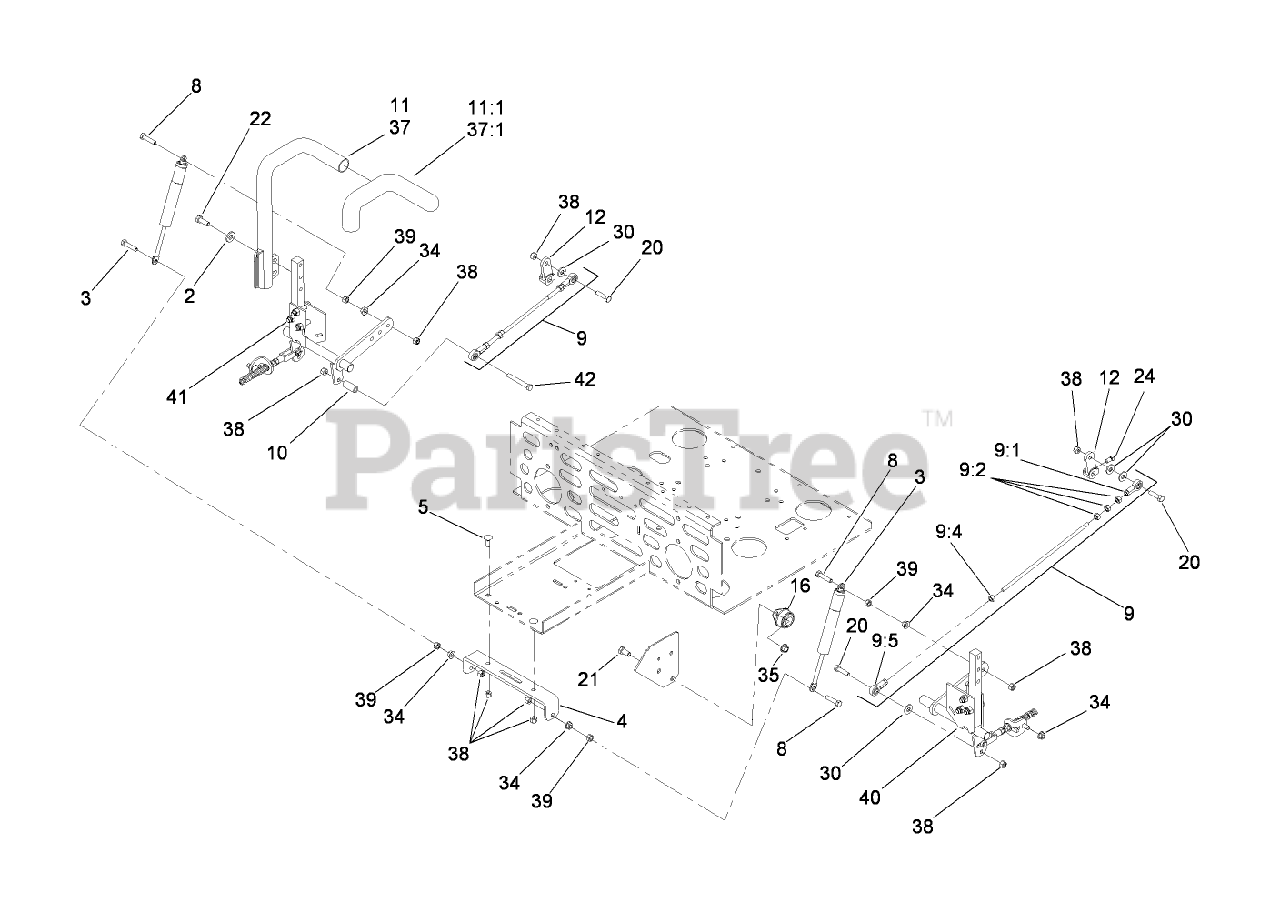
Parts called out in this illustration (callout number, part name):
2	WASHER-BELLEVILLE
3	DAMPER-CONTROL, MOTION
4	BRACKET-MOUNT, DAMPER
5	SCREW-CARR
8	SCREW-HH
9	Tracking Rod ASM
9:1	BALLJOINT-RH
9:2	NUT-HEX
9:5	BALLJOINT-LH
10	SPACER
11	LH LEVER ASM
11:1	Grip-Control, Motion
12	ARM-CONTROL, PUMP
16	BEARING-FLANGE, SIDE
20	SCREW-HH
21	SCREW-HH
22	SCREW-HH
24	SCREW-SET
30	WASHER-FLAT
34	NUT-HF
35	NUT-HHF, WHIZ
37	RH LEVER ASM
37:1	Grip-Control, Motion
38	NUT-LOCK, NI
39	NUT-HEX
40	LH MOTION CONTROL ASM
41	RH MOTION CONTROL ASM
42	SCREW-HH
